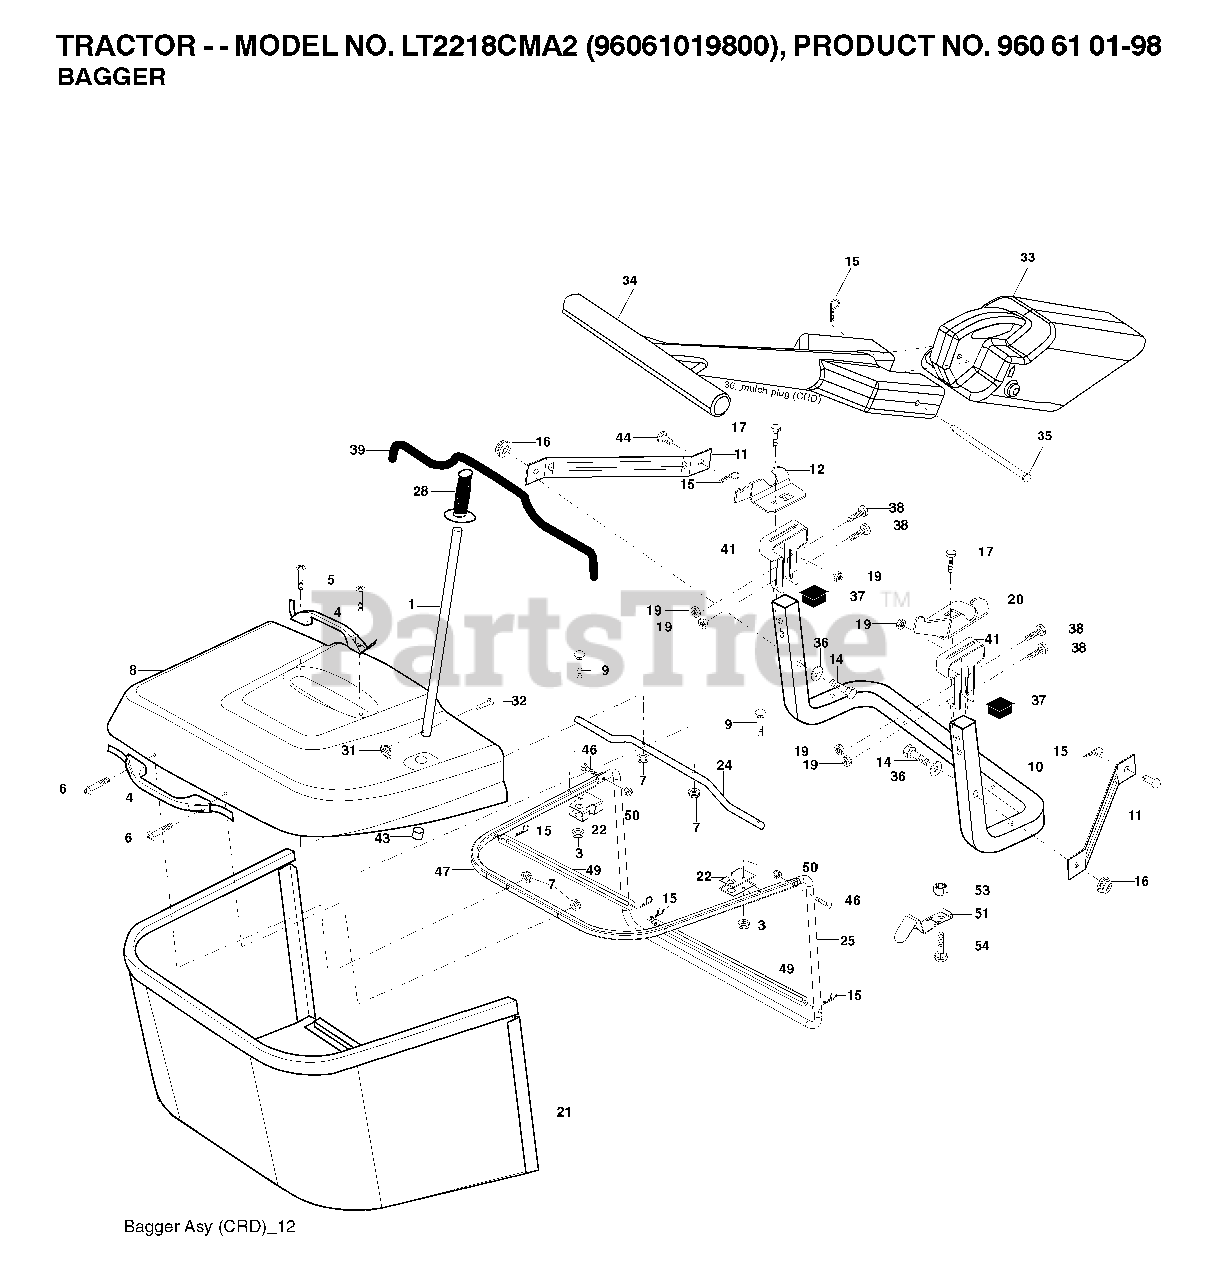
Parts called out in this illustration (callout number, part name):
1	TUBE HANDLE
3	NUT T
5	SCREW.PAN.HEAD
11	BRACKET
14	BOLT-HEX EAK
15	RETAINER-SPRNG RB
16	NUT LOCK FLG 3/8-16 UNC
17	BOLT
19	NUT LOCK HEX FLANGE 5/16-18
20	BRKT.PIVOT.RH.CRD
21	BAGGER.ASM.CRD.2007
22	BRACKET
24	TUBE
28	GRIP.HANDLE.BLACK
31	RETAINER CLIP
32	RIVET,DRILLED
33	MULCH PLUG, CTH150
35	PIN
38	BOLT.5/16-18X2.5
41	BRKT, BAGGER
43	PLUG, TUBING END
46	BOLT.CARRIAGE.5/16-18
50	NUT.71038.31-18.HEX.NYLOCK
53	NUT
54	BOLT
